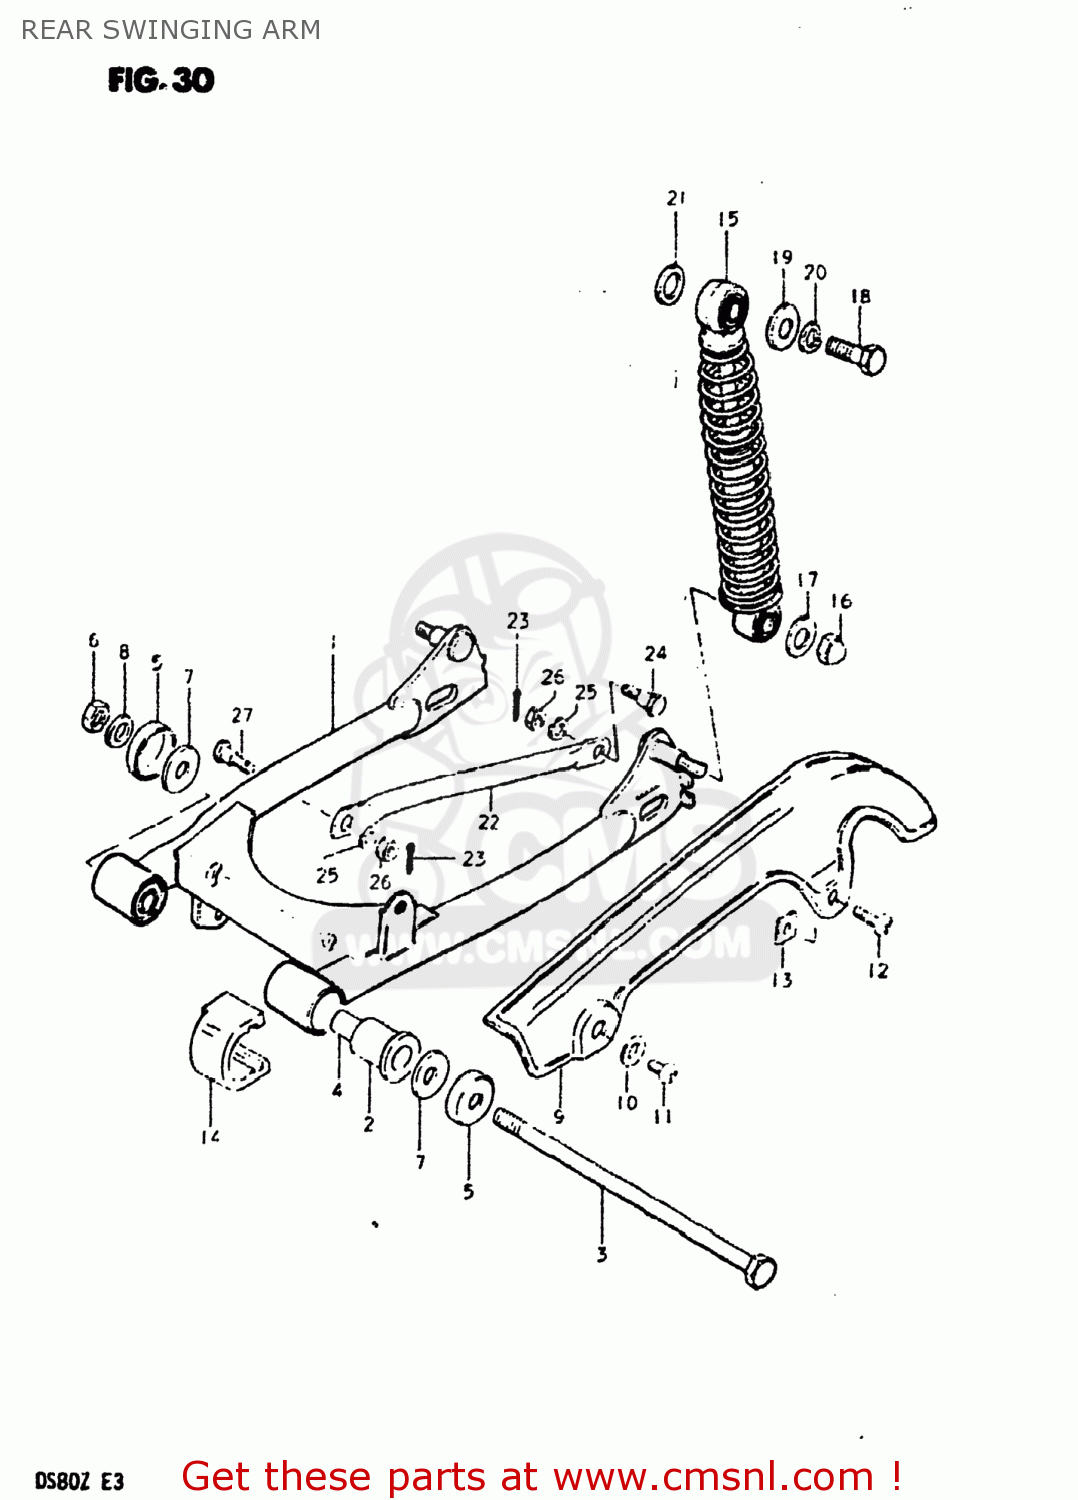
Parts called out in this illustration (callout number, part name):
1	SWING ARM ASSEMBLY,REAR
2	BUSHING
3	SHAFT, PIVOT
4	SPACER,RR SWGARM PIVOT
5	COVER,REAR SWING ARM DUST
6	NUT
7	WASHER (10.2X28X1.5)
8	WASHER
9	CASE,CHAIN
10	WASHER
11	SCREW
12	SCREW 6X12
13	NUT,CHAIN CASE RR
14	BUFFER,CHAIN TOUCH DEFLECTOR
15	ABSORBER ASSEMBLY,REAR SHOCK
16	NUT, LOWER LH
17	WASHER
18	BOLT
19	WASHER (6.5X24X1.6)
20	LOCK WASHER
21	WASHER
22	TORQUE LINK,REAR
23	COTTER PIN
24	BOLT(8X26.5)
25	LOCK WASHER
26	NUT
27	BOLT(8X22)
